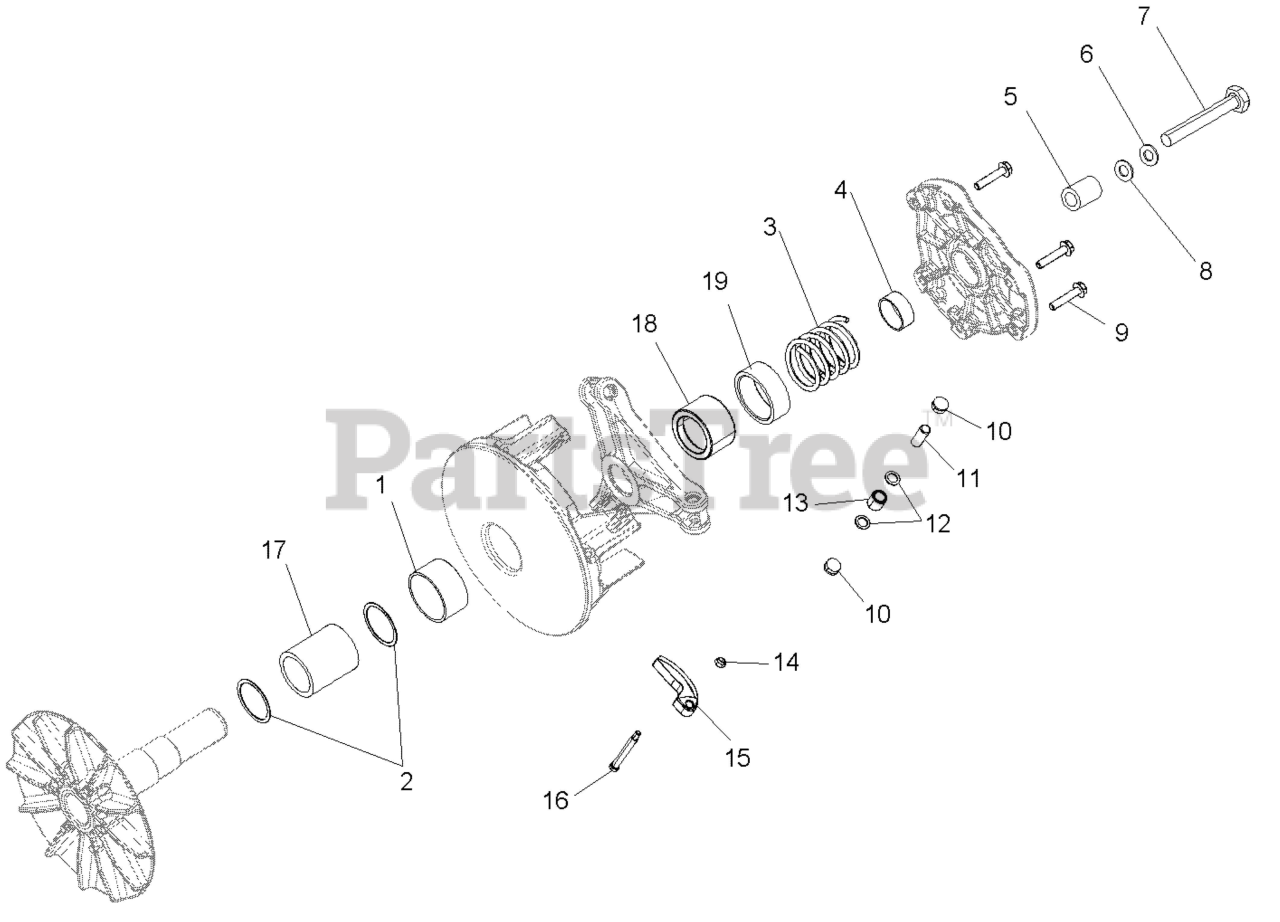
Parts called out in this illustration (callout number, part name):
1	BEARING-DU,1.75ID
2	WASHER-CLUTCH,VESPEL
3	SPRING-CLUTCH, 35-240
4	BEARING COVER, .75IN
6	WASHER LOCK
7	BOLT-CLUTCH ATV,7/16X20X8
8	WASHER(10) *
9	SCR-1/4-20X1.25 HX/FL GR5
10	BUTTON,CLUTCH,RUBBER BACKED
11	PIN-ROLLER,(10)
12	WASHER-CLUTCH,SPIDER ROLLER
12	WASHER
13	ROLLER/BUSHING ASM.(3) **
14	NUT FLEXLOC(10)
15	WEIGHT-SHIFT,25-52G,PM
16	BOLT,SHOULDER(10)
17	BEARING-NEEDLE
18	SPACER-CLUTCH
19	SPACER-CLUTCH,LIMITER
